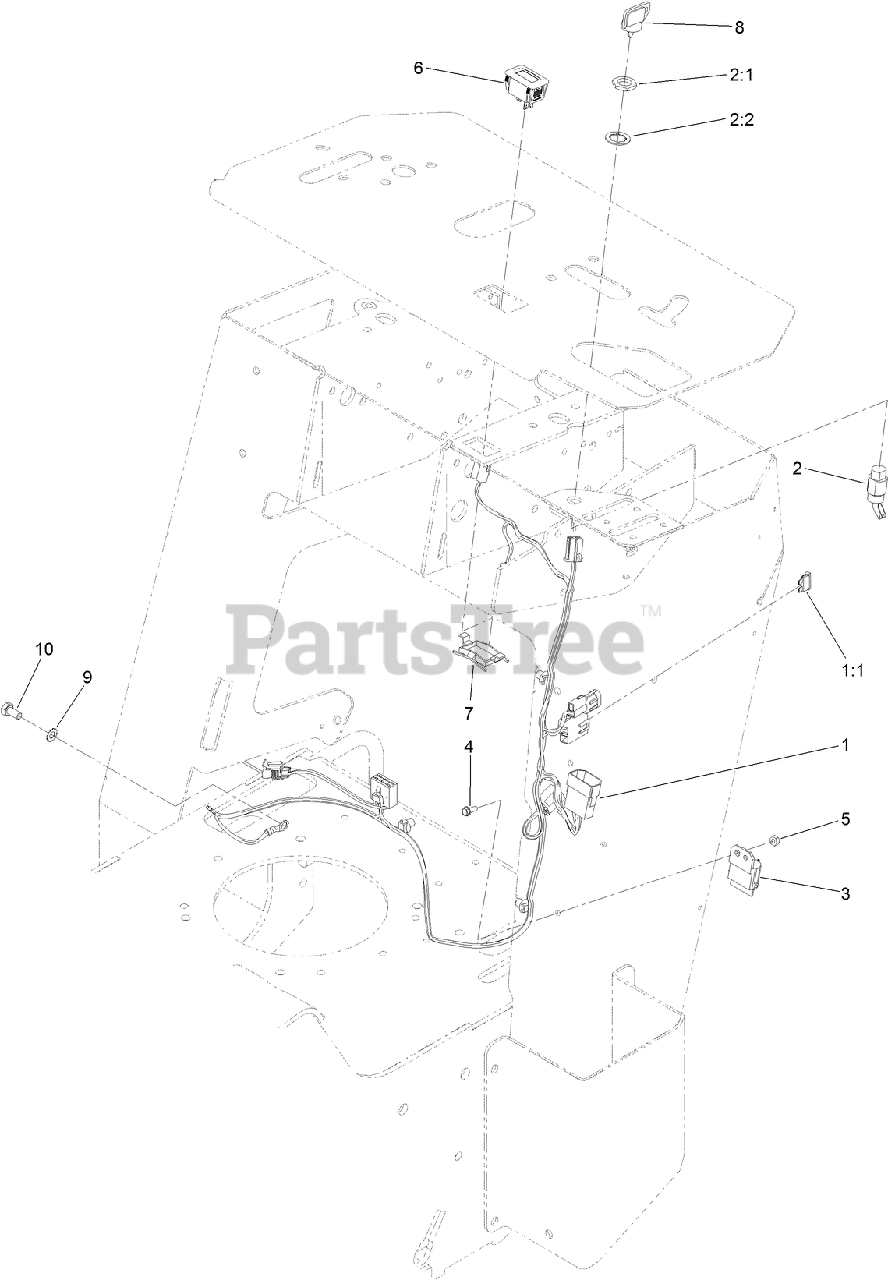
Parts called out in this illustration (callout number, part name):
1	HARNESS-WIRE
1:1	FUSE-BLADE, 15 AMP
2	SWITCH-ON / OFF
2:1	NUT-HH
2:2	WASHER-LOCK
3	MODULE-INTERLOCK
5	NUT-LOCK, NI
6	HOURMETER
7	CLIP-MOUNTING
8	KEY-IGNITION
9	WASHER-LOCK
10	SCREW-HH
